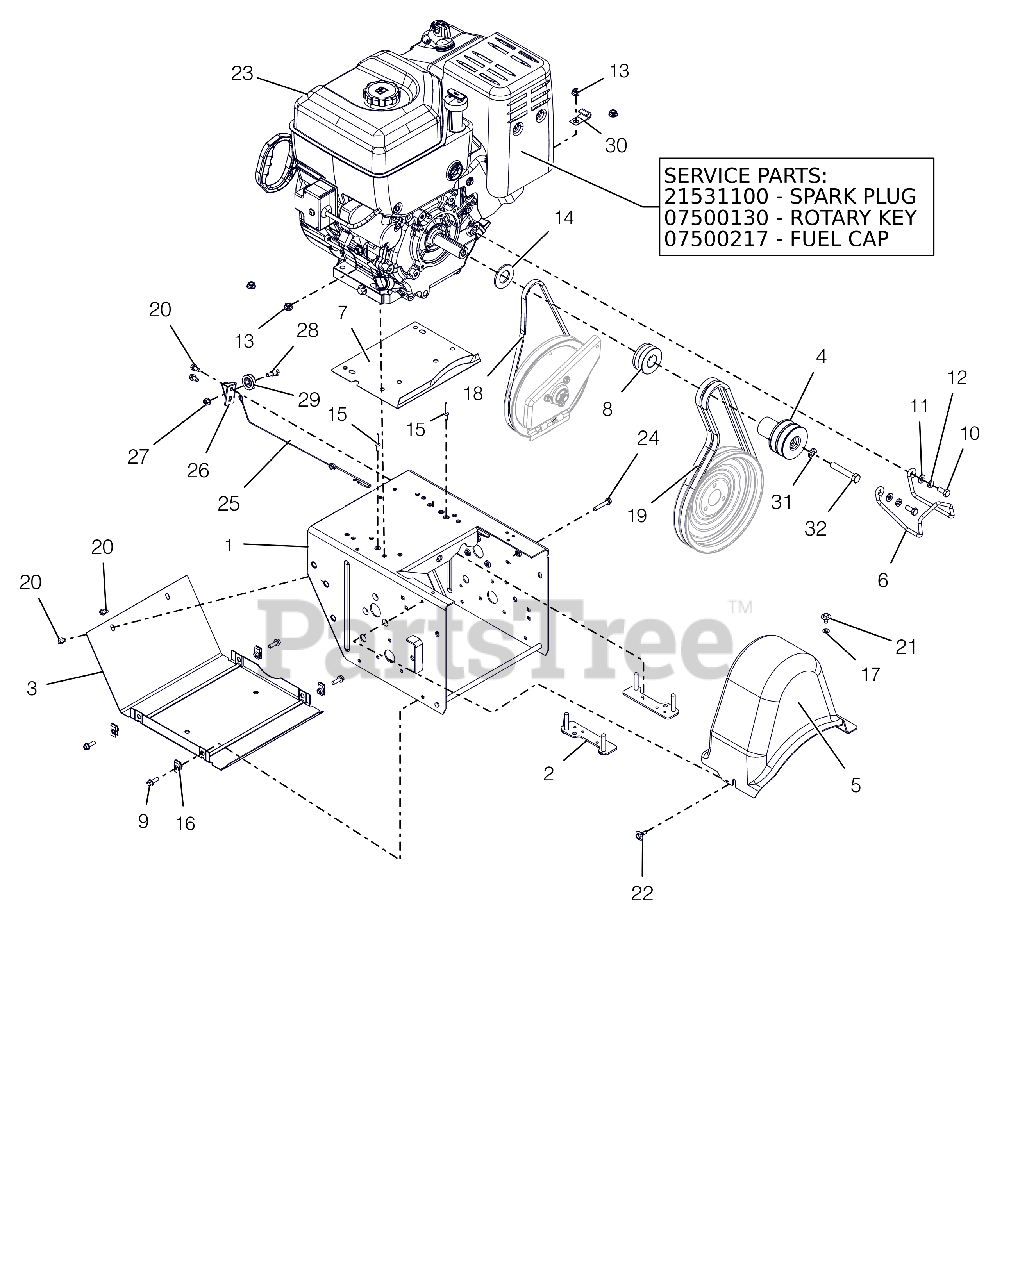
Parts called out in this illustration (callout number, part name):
1	FRAME, MAIN - PRO (WELDMENT)
2	STRAP, BOLT-LARGE
3	COVER, BOTTOM
4	SHEAVE, ATTACHMENT 2-GRV
5	COVER, BELT-LARGE
6	FINGER, BELT
7	BAFFLE, WATER - LARGE BLOCK
8	SHEAVE, DRIVE
9	BLT-HEX .25-20X.75 HWH YZ GR5
10	BLT-HEX .31-24X.75 YWZC GR5
11	@WSHR-FL-STL.344X.688X.065YWZC
12	WSHR-LK .312X.097 HVY YWZC
13	@NUT-LK-CTR-FLG .31-18 YZ GR F
14	WSHR-FL-STL- 1.062X2.0X.134 YZ
15	RVT-POP .187 YZ
16	NUT-RTNR .25-20X.56
17	NUT-PUSH .25X.50 O.D.
18	V-BELT, 3L-WRAPPED
19	V-BELT, HA-RAW EDGE (SET)
20	SCR-TAP .25-20X.50 HWH TR YWZ
21	SCR-TAP .25-20X.50 LGHWH TR YZ
22	SCR-TAP .25-20X.5 CAPTIVE
23	ENGINE, BRIGGS PF 2100, 240V
23	PLUG, SPARK 20HP B&S VANGUARD
23	KEY, IGNITION ROTARY B&S
23	CAP, FUEL - BRIGGS & STRATTON
24	@SCR-TAP .25-20X1.50 HWH TR YZ
25	CABLE, LOWER TRACTION,SS & PRO
26	BRACKET, CABLE PULLEY
27	@NUT-LK-TOP-FLG .25-20 YWZC
28	BOLT, SHLDR-.375X.375X.25-20
29	PULLEY, CABLE
30	J-CLAMP
31	@WSHR-LK .44X.109 REG YWZC
32	BLT-HEX .44-20X2.50 GR5 YWZC
